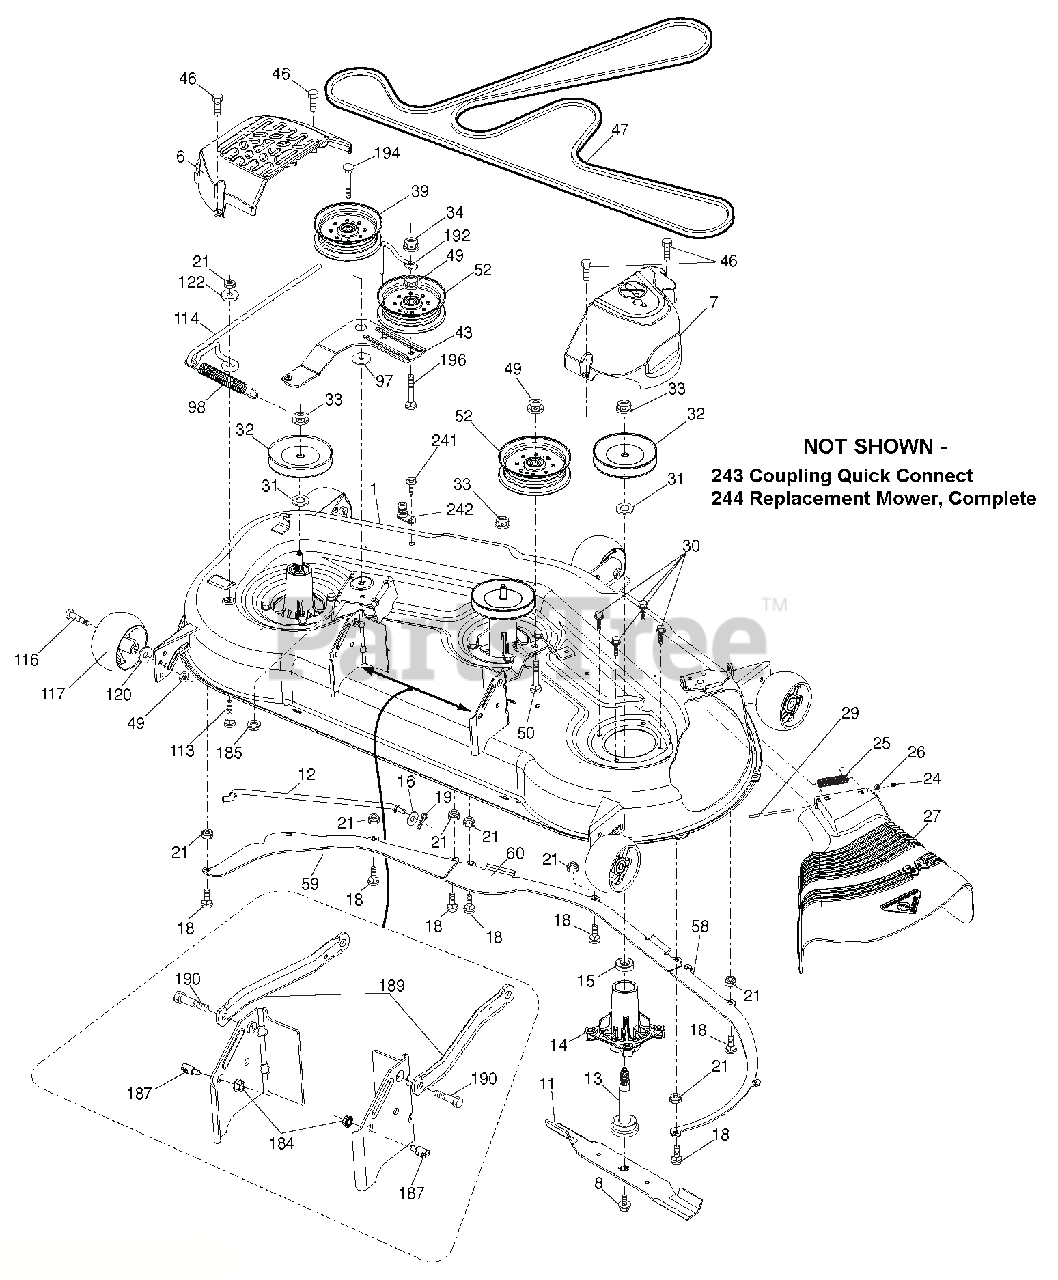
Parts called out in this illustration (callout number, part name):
1	DECK WELDMENT MOWER
6	COVER.MANDREL.LH.54"2006
7	COVER.MANDREL.RH.54"2006
8	BOLT/WASHER ASM.7/16-20.UNF
11	BLADE.BAGGING.54"
12	ROD.ANTI SWAY.48/54"K46.TEX
13	SHAFT ASM.MANDREL.48/54"SVC
14	HOUSING.MANDREL.4PT.SERVICE
15	BEARING.BALL.MANDREL
16	Washer 13/32 x 13/16 x 12 Ga.
18	BOLT.RDHD.SQNK.5/16-18 X 5/8
19	PIN.COTTER.5/16.BOW TIE LOCK
21	Nut, Hex, Crownlock 5/16-18
24	CAP.SLEEVE..80X.112.BLK.MOWER
25	SPRING.TORSION.48"
26	NUT.PUSH.PHOS.& OIL
27	DEFLECTOR SHIELD
29	ROD.HINGE.42/46"
30	SCREW.THD ROLL.DOD PT.HEX
31	WASHER.SPACER.MANDREL
32	MANDREL.PULLEYS.42,44,50
32	MANDREL ASM.48/54"
32	(KEY# 14), SHAFT ASSEMBLY (KEY# 13) AND
32	BEARING (KEY# 15) ONLY - PULLEY/NUT/WASHER
32	AND BLADE BOLT/WASHERS NOT INCLUDED)
33	NUT.FLANGE.LOCK.TOP
34	Nut, Hex, Crownlock 3/8-16
39	PULLEY.IDLER.4.50.HUB.SPECIAL
43	ARM.ILDER
46	SCREW.THD.ROLL.1/4-20 X 5/8
47	BELT.DRIVE.54"2006
49	Nut, Hex, Flangelock 3/8-16
50	BOLT.RD.HD.SQ.NK.3/8-16UNC X 2
52	PULLEY.IDLER.4.50.RAW
58	BAFFLE.RIGHT.54"
59	BAFFLE.LEFT.54"
60	BAFFLE.CENTER.54"MOWER
97	WASHER.FLAT.HARDENED
98	SPRING.DRIVE.DECK.2006
113	BOLT.CARR.5/16-18UNC X 1
114	ROD.TENSION.RELIEF
116	BOLT.SHOULDER.3/8-16X3-5/8.GR5
117	WHEEL.GAUGE.RALLY.
120	WASHER.13/32 X 1-1/4 X 12 GA.
122	BUSHING.RELIEF.TENSION
184	Nut, Lock Hex Flange 5/16-18 u
185	NUT.LOCK.FLANGE.7/16-14.GR5
187	STUD.FASTNER.W/'D'ANTI-ROTATIO
189	ARM.SUSPENSION.MOWER.REAR
190	BOLT.SHOULDER
192	KEEPER.BELT.IDLER.54"TL
194	BOLT CARR SQNK 3/8-16 X 2-1/4
196	BOLT.RDHD.SQNK.3/8-16X2-1/2.G5
242	PORT WASHOUT
243	COUPLING QUICK CONNECT
244	54" REPLACEMENT MOWER COMPLETE
